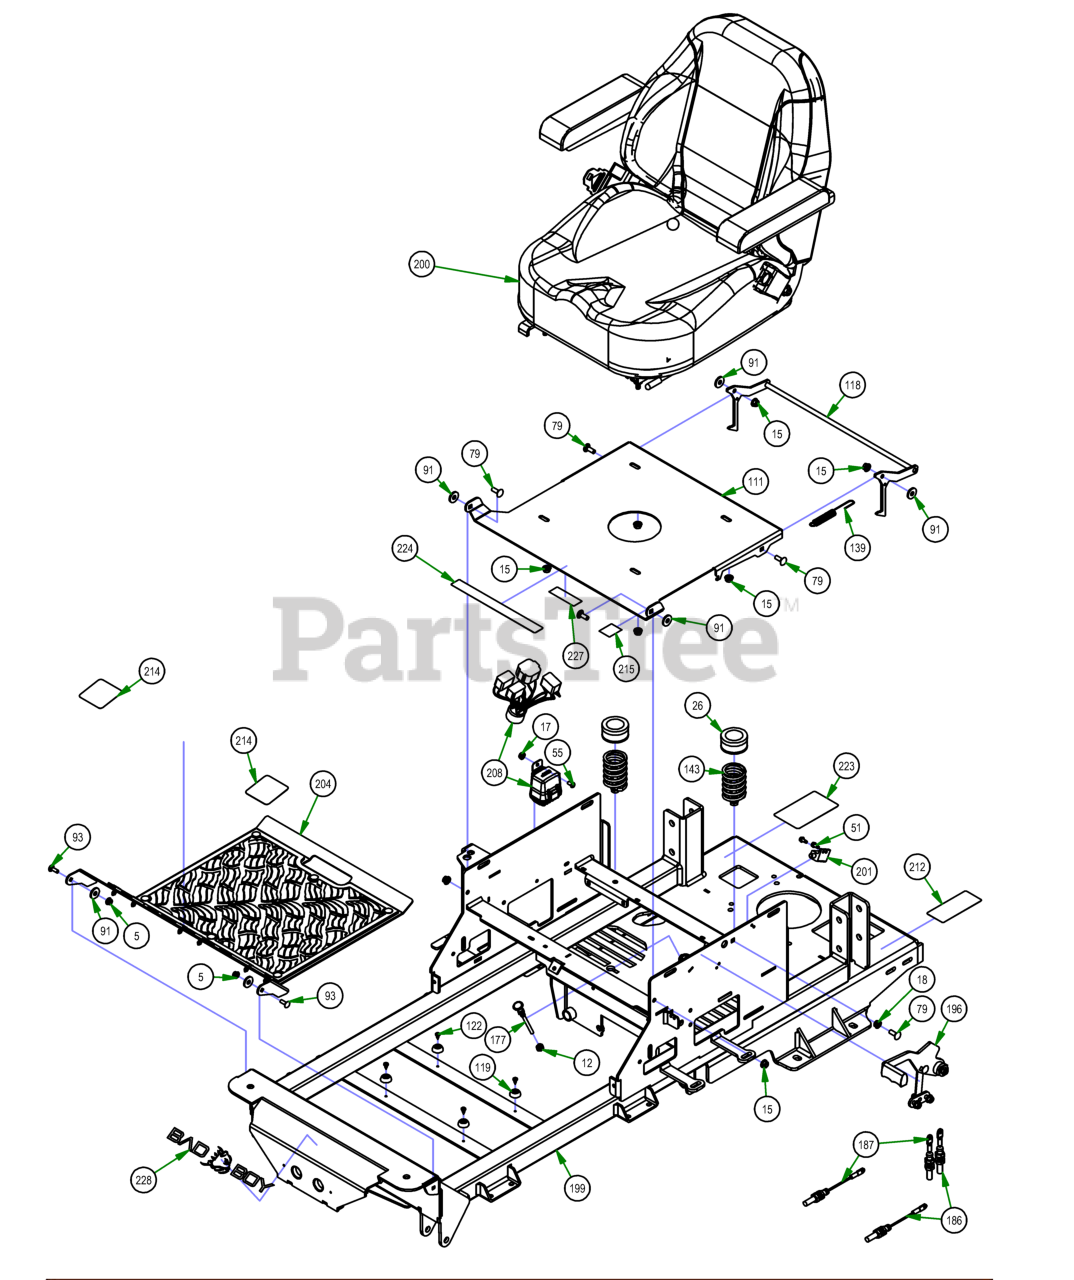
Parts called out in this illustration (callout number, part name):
5	1/4-20 NYL INSERT FLANGE LOCKNUT ZINC
12	3/8-24 HEX NUT ZINC YELLOW
15	5/16-18 NYLON INSERT FLANGE LOCKNUT ZINC
17	1/4-20 HEX SERRATED FLANGE NUT HARD/ZINC
18	5/16-18 HEX SERRATED FLANGE NUT HARD/ZINC
26	Seat Spring Cap Cover
51	12-24 X 1/2 HEX WASHER UNLSOT F TCS ZINC
55	1/4-20 X 1/2 BUTTON SOCKET CAP SCREW 18-8 STAINLESS STEEL
79	5/16-18 X 7/8 CARRIAGE BOLT ZINC
91	.360 ID X .983 OD X .120 THICK FLAT WASHER NYLON
93	1/4-20 X 3/4 CARRIAGE BOLT (GR.5) ZINC
110	2021 Maverick Rear Cover Assembly
111	Seat Plate 2016
118	Seat Latch Rod Assembly
119	Button Bumper
122	10-16 X 1/2 PAN PHIL TEK/3 CLIMASEAL OR ACF-SILVER COATED
139	Brake Spring
143	Seat Spring Assembly
186	2021 Load Balanced Brake Cable 1
187	2021 Load Balanced Brake Cable 2
196	2021 Load Balanced Brake Handle Assembly
199	2021 Maverick Frame - Painted
200	2021 Maverick Seat
201	Safety Switch
204	2021 Maverick Floorboard Assembly
208	Wiring Harness
212	EPA Build Date Punch Label
214	2018 Maverick/2021 ZT Anti-Skid Steering Control Decals
215	2018 MZ/Magnum/ZT/MAV/Comp Out Brake Decal
223	Maverick Pump Belt Decal
224	Outlaw Warning Decal
227	Not For Sale In California
228	Flying Bulldog Front Bumper Decal
